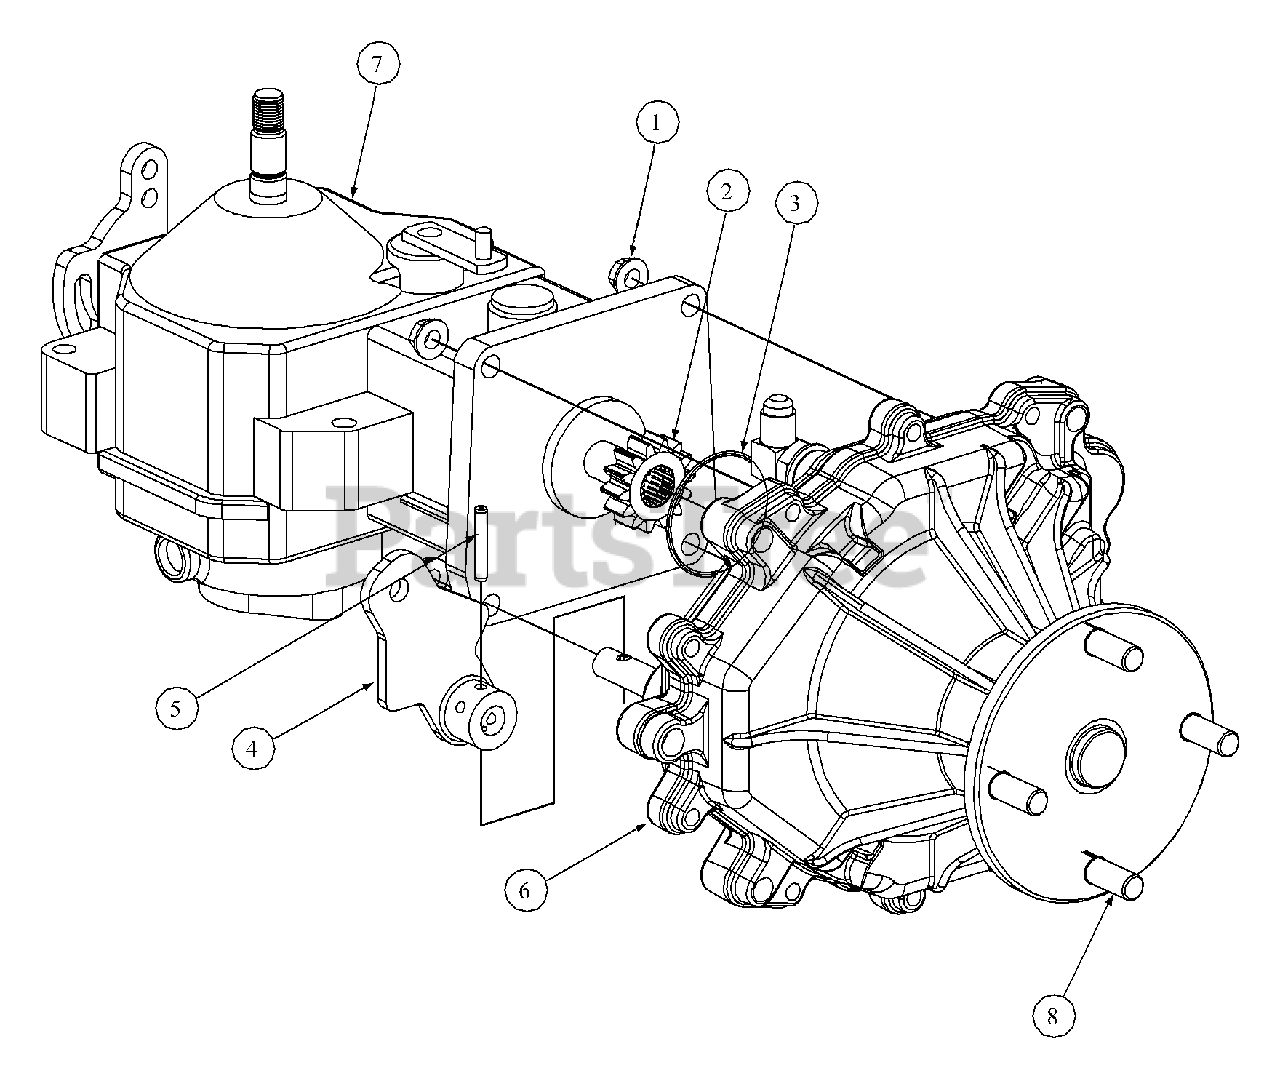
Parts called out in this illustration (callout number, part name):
1	Hex Flange, Lock Nut, 5/16-18
2	Gear, Spur, 14T
3	O-Ring, 2.00 x .070
4	Lever, Bracket, Park
5	Pin, Spirol, 3/16 x 1.25 HD
6	Transmission Assembly
7	Pump
8	rib Neck Stud 1/2-20
